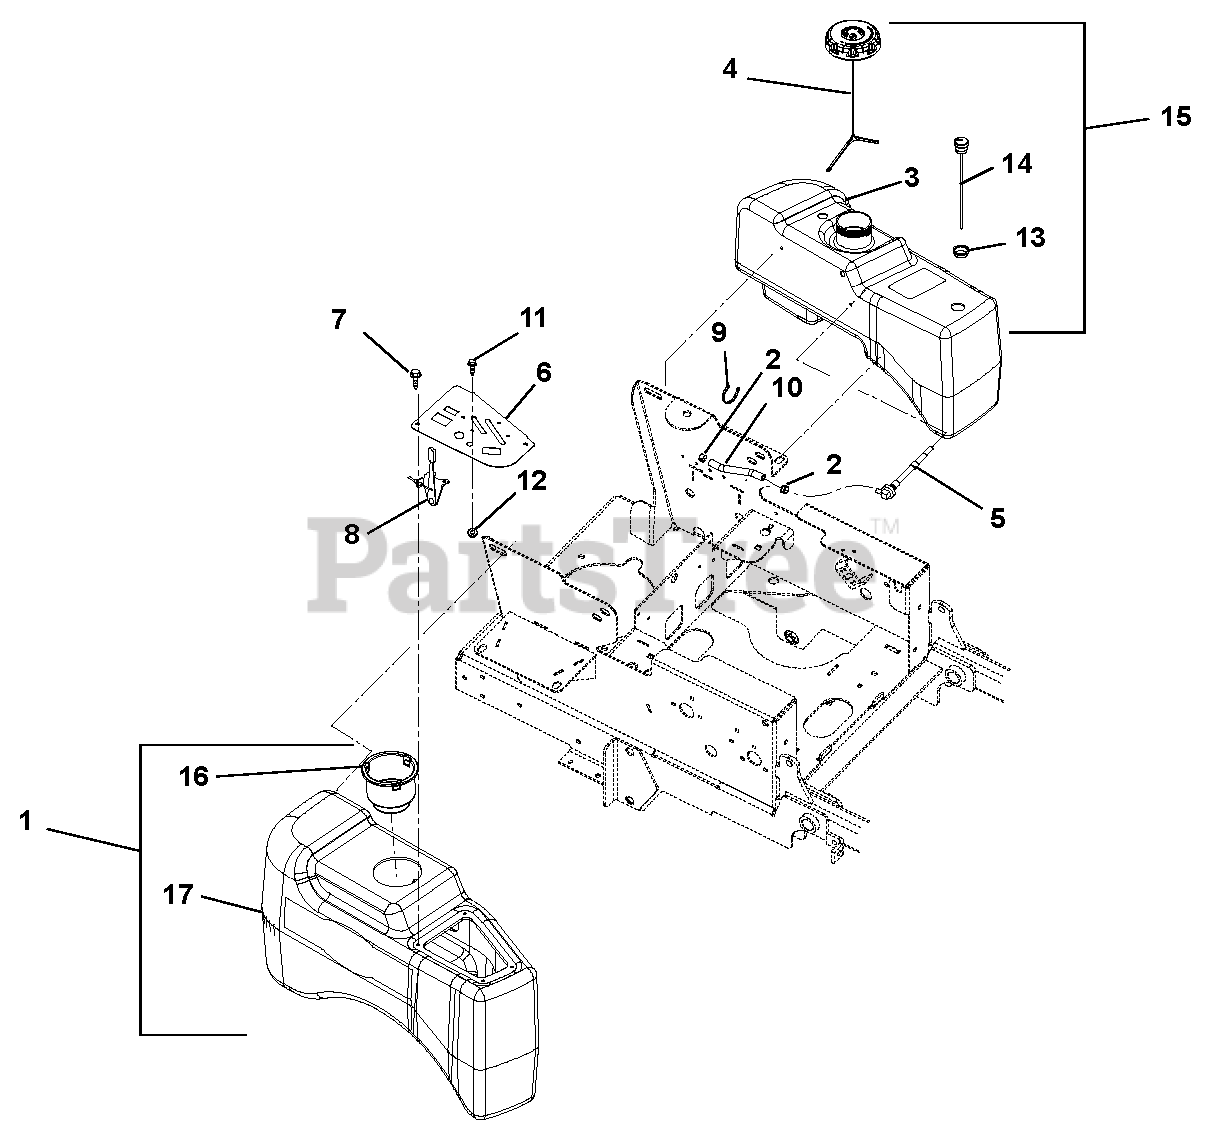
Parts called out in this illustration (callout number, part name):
1	Assembly, Fender with Cupholder (Includes items 16 and 17)
2	Clamp, Fuel Line
3	Tank, Fuel Left Hand
4	Cap, Fuel Vent-in Autolock (991082, 083, 084, 090)
4	Cap, Fuel Non-Vent Autolock (991098, 099, 100, 101)
5	Assembly, Tank Fuel Pick-up
6	Panel, Control
7	Screw, Plastite .25 x 10 x .75 YZ
8	Cable, Control (991082, 083, 084, 090, 098, 099, 100, 101)
9	Cable Tie
10	Hose, .25 Low-PERM Bulk Gas
11	Screw, Machine 10-24 x .50 Hex Washer Head
12	Nut, Locking Nylon 10-24 with Insert
13	Grommet, Fuel Gauge
14	Gauge, Remote Fuel 10.0"
15	Assembly, Fuel Tank (Includes items 3, 4, 5, 13, 14 above and items 1, 2 on page 11)
16	Cupholder
17	Fender
